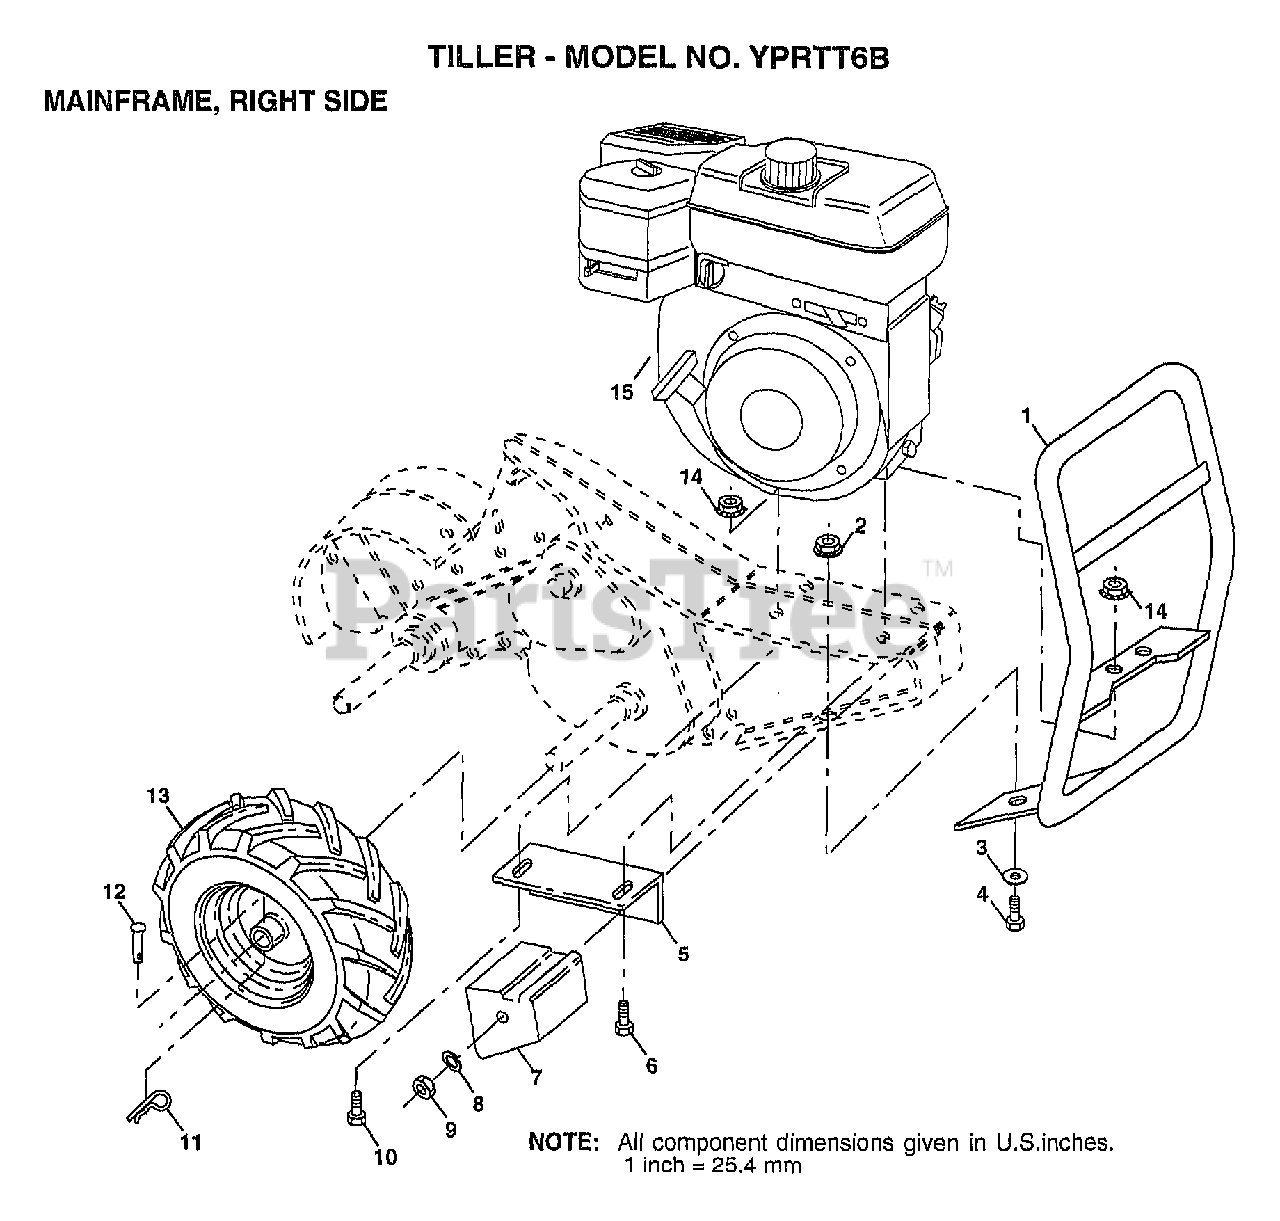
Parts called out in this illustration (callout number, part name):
1	BUMPER ASM.TILLER
2	LOCKNUT TI
3	WASHER
4	BOLT
5	BRACKET RH CRT
6	BOLT
7	COUNTERWEIGHT CRT
8	LOCKWASHER
9	NUT.HEX.3/8-16UNC
10	BOLT.HEX.5/16-1.5
11	RETAINER M
12	RIVET.DRILL.1.75
13	TIRE TI
13	RIM
